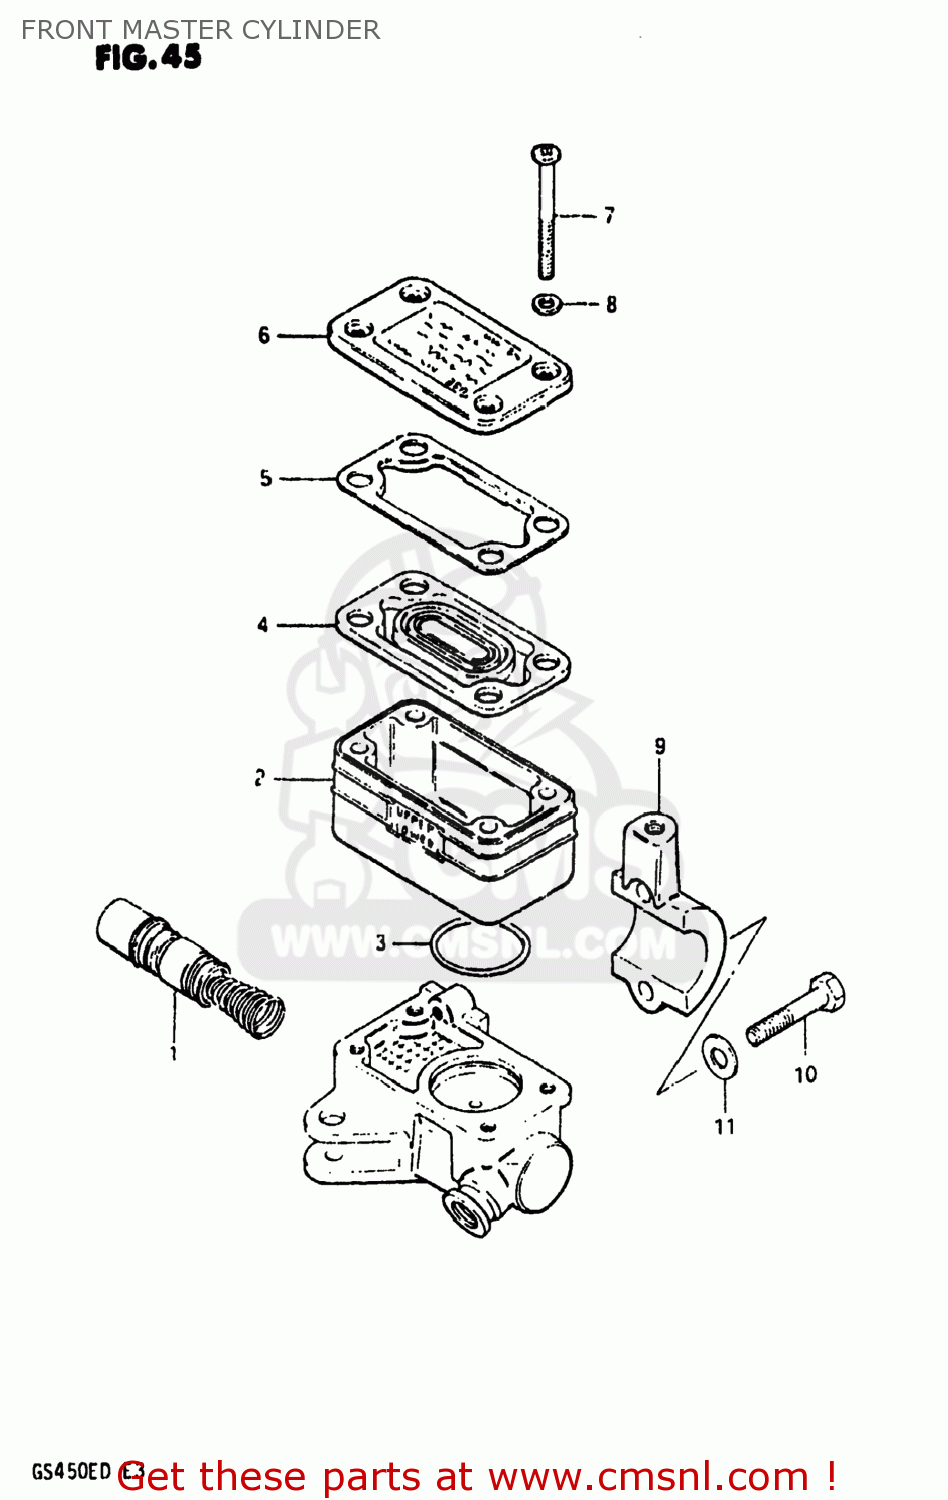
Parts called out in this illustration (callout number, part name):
1	PISTON & CUP SET
2	RESERVOIR
3	O RING
4	DIAPHRAGM
5	PLATE,DIAPHRAGM
6	CAP
7	SCREW
8	WASHER
9	HOLDER
10	BOLT
11	WASHER
